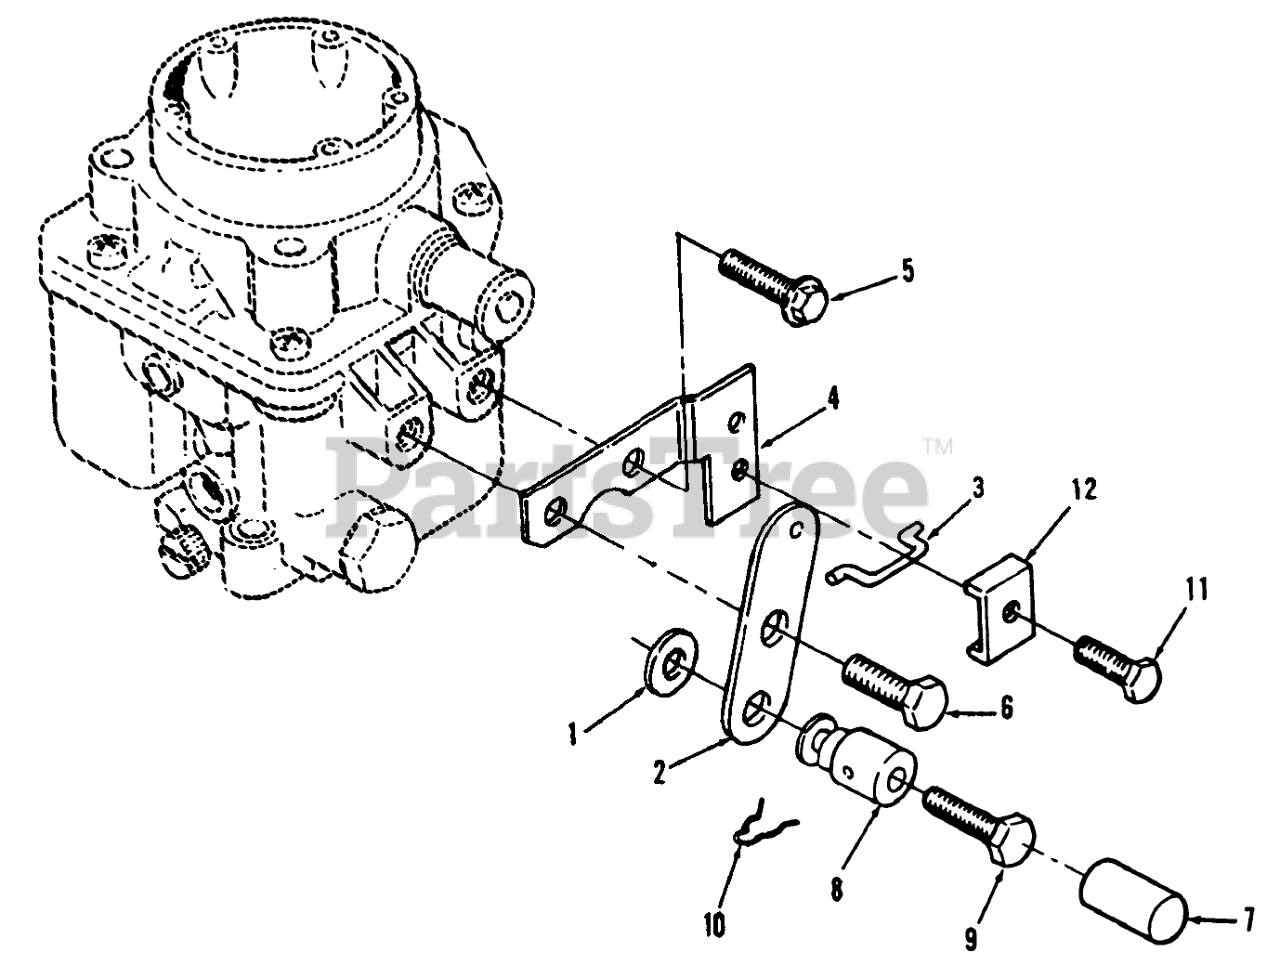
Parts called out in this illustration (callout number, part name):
1	Washer
2	SWIVEL-CHOKE
3	LINK-CHOKE
4	BRACKET
5	Bolt
6	MACHINE SCREW
8	SWIVEL
9	Bolt
10	PIN-COTTER
11	Bolt
